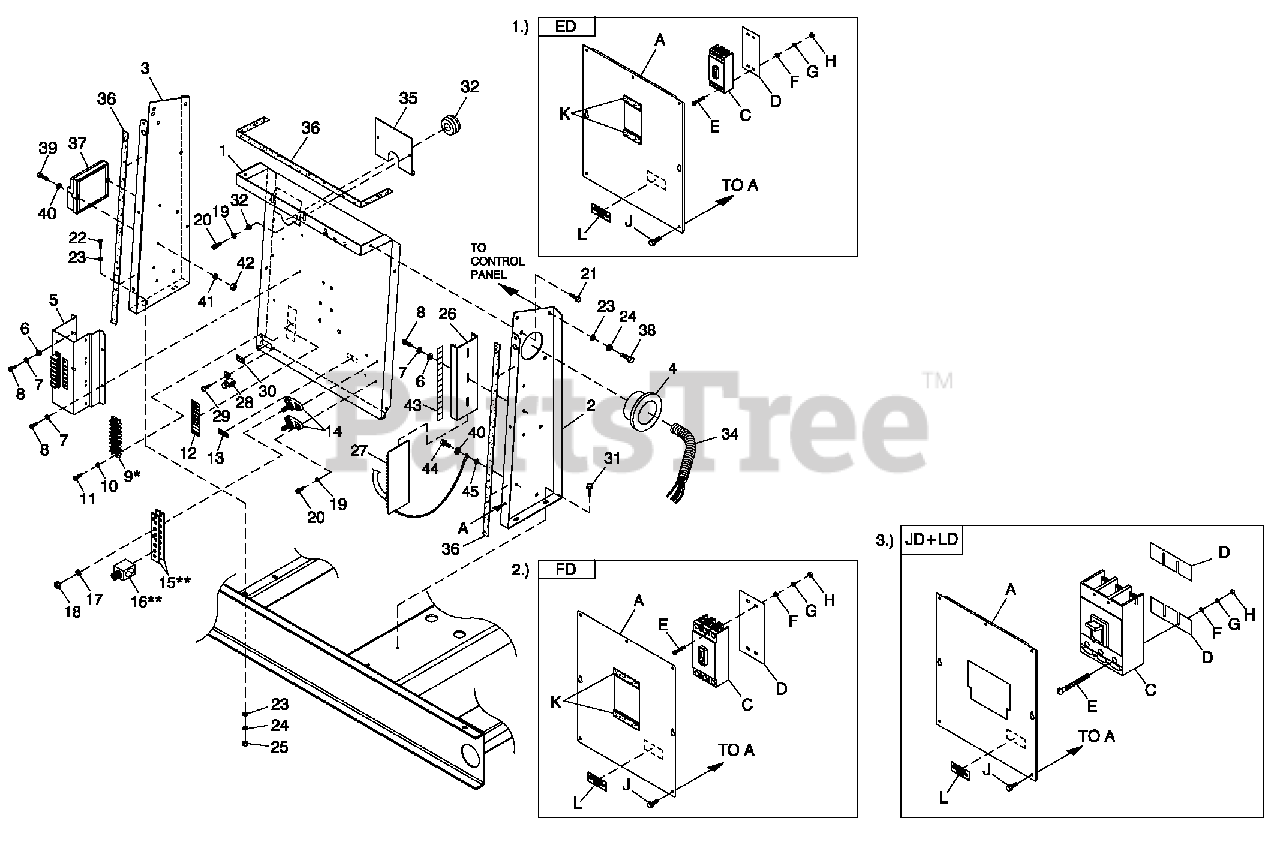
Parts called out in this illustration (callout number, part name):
1	PAN CB CONN BOX
2	STAND RH CONTROL
3	STAND LH CONTROL
4	BUSHING SNAP SB-2.5-31
5	ASSY PCB INTERFACE 1PH 240V
6	WASHER FLAT M4
7	WASHER LOCK #8-M4
8	SCREW PHTTM4-0.7X 10 ZYC
9	BLOCK TERM 20A 8 X 6 X 1100V
10	WASHER LOCK#6
11	SCREW PHTT #6-32X1/2 ZYC
12	DECAL CPL CUST CONN H CTRL
13	DECAL NEUTRAL
14	JUNCTION BLOCK 3/8-16
15	BUS BAR NEUTRAL BLOCK 390
16	LUG SLDLSS 600/250-1/0 X 1/4-28
17	WASHER LOCK 3/8
18	NUT HEX 3/8-16 STEEL
19	WASHER LOCK M5
20	SCREW PHTT M5-0.8X 16 ZYC
21	SCREW THF M6-1 X 16 N WA Z/JS
22	SCREW HHCM6-1.0X 20 G8.8
23	WASHER FLAT 1/4-M6 ZINC
24	WASHER LOCK M6-1/4
25	NUT HEX M6 X 1.0 G8 YEL CHR
26	RAIL SNAPTRACK PCB HOLDER BULK
27	ASSY RELAY PCB 12VDC
28	LUG SLDLSS #6-14X 13/64CU
29	SCREW HHTT #10-32X3/8 CZ
30	DECAL GROUND LUG
31	SCREW HHTT M6-1.0X 16 ZYC
32	WASHER FLAT M5
33	GROMMET 1.25 X .25 X .75
34	CONDUIT FLEX 2.0" ID
35	PLATE WIRE SNGLGALV
36	TAPE ELEC 1/2 FOAM (AS REQ'D)
37	ASSY PCB HSB CTRL IGN MODULE
38	SCREW HHC M6-1.0X 16G8.8
39	SCREW PPHM #10 /32X2
40	WASHER FLAT #10 ZINC
41	WASHER LOCK #10
42	NUT HEX #10-32 STEEL
43	DECAL H-100 RB3 CUST CONN
44	SCREW HHTT M4-0.7X 8 ZP
45	WASHER SHAKEPROOF EXT #10 STL
A	COVER ED CB STAND C3
C	CB0090A3P 480V SED4 LL
D	INSULATOR CBS(ED-3P)
E	SCREW RHM #10-32X4-1/2
F	WASHER FLAT #10 ZINC
G	WASHER LOCK #10
H	NUT HEX #10-32 STEEL
J	SCREW THF M6-1 X 16 N WA Z/JS
K	TAPE ELEC 1/2 FOAM (AS REQ'D)
L	DECAL CUSTOMER CONNECT INSIDE
A	COVER FD CB STAND C3
C	CB0175A3P 600V SFD6 LL
D	INSULATOR CB FD FRAME 30MIL
E	SCREW SHC 1/4-20 X 4 G8.8 NZ
F	WASHER FLAT 1/4-M6 ZINC
G	WASHER LOCK M6-1/4
H	NUT HEX 1/4-20 STEEL
A	COVER JD/LDCB STAND C3
C	CB0300A3P 600V SJD6 LL
D	INSULATOR CIRCUIT BR. JD/LD
E	SCREW RHM 1/4-20X3
